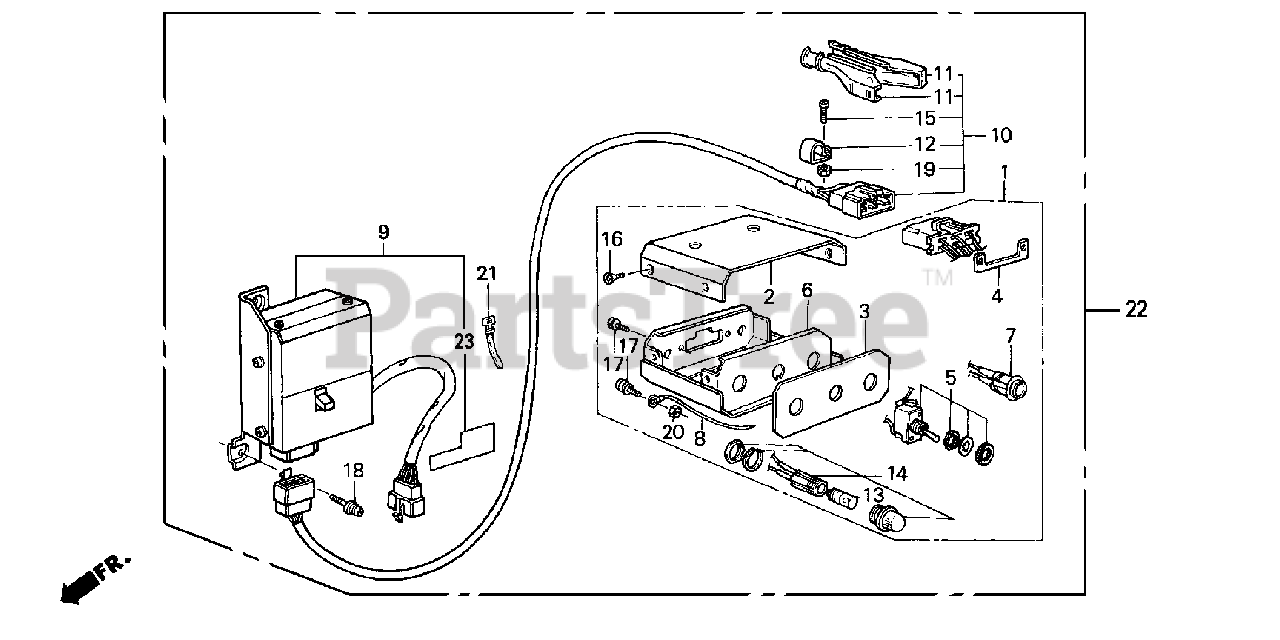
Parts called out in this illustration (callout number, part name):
1	BOX ASSY., SWITCH *R8*
2	COVER (UPPER) *R8*
3	PLATE, SWITCH & INDICATOR
4	PLATE, CONNECTOR SETTING
5	SWITCH, TOGGLE
6	PANEL, CONTROL *R8*
7	SWITCH, PUSH
8	WIRE, GROUND
9	BOX ASSY., RELAY
10	CABLE, REMOTE CONTROL (10MM)
11	COVER, CONNECTOR
13	BULB, WEDGE BASE (12V/2W)
14	SOCKET ASSY., LAMP (GREEN)
15	SCREW, PAN (3X12)
16	SCREW, FLAT (4X8)
17	SCREW-WASHER (4X12)
18	SCREW-WASHER (6X25)
19	NUT, HEX. (3MM)
20	NUT, HEX. (4MM)
21	BAND B1, CABLE
22	REMOTE CONTROL KIT *R8*
23	MARK, REMOTE CONTROL
